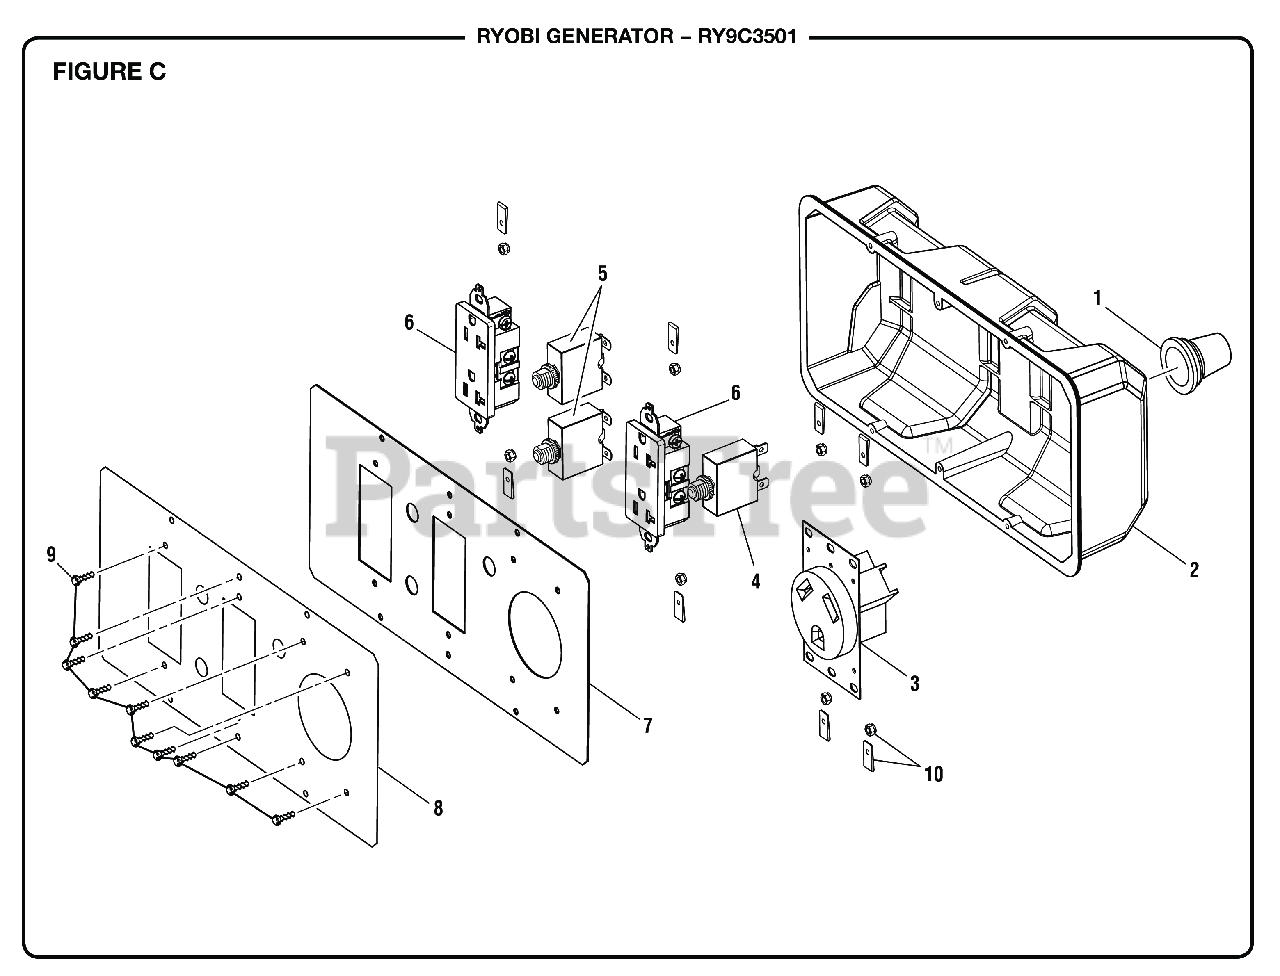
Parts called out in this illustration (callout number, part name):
1	Wiring Rubber Boot
2	Control Box (Back Panel)
3	Twist Lock Receptacle (120 Volt, 30 Amp)
4	Circuit Breaker 30 Amp 1 Pole
5	Circuit Breaker (20 Amp, 125 Volt)
6	120 Volt Duplex Receptacle (BM903600)
7	Cover Plate
8	Electrical Outlet Label
9	Screw (6-20 x 3/8 in., Phillips Pan Hd.)
10	Lock Nut (6-32, Hex Hd.)
10	U- Clip Nut (#6)
